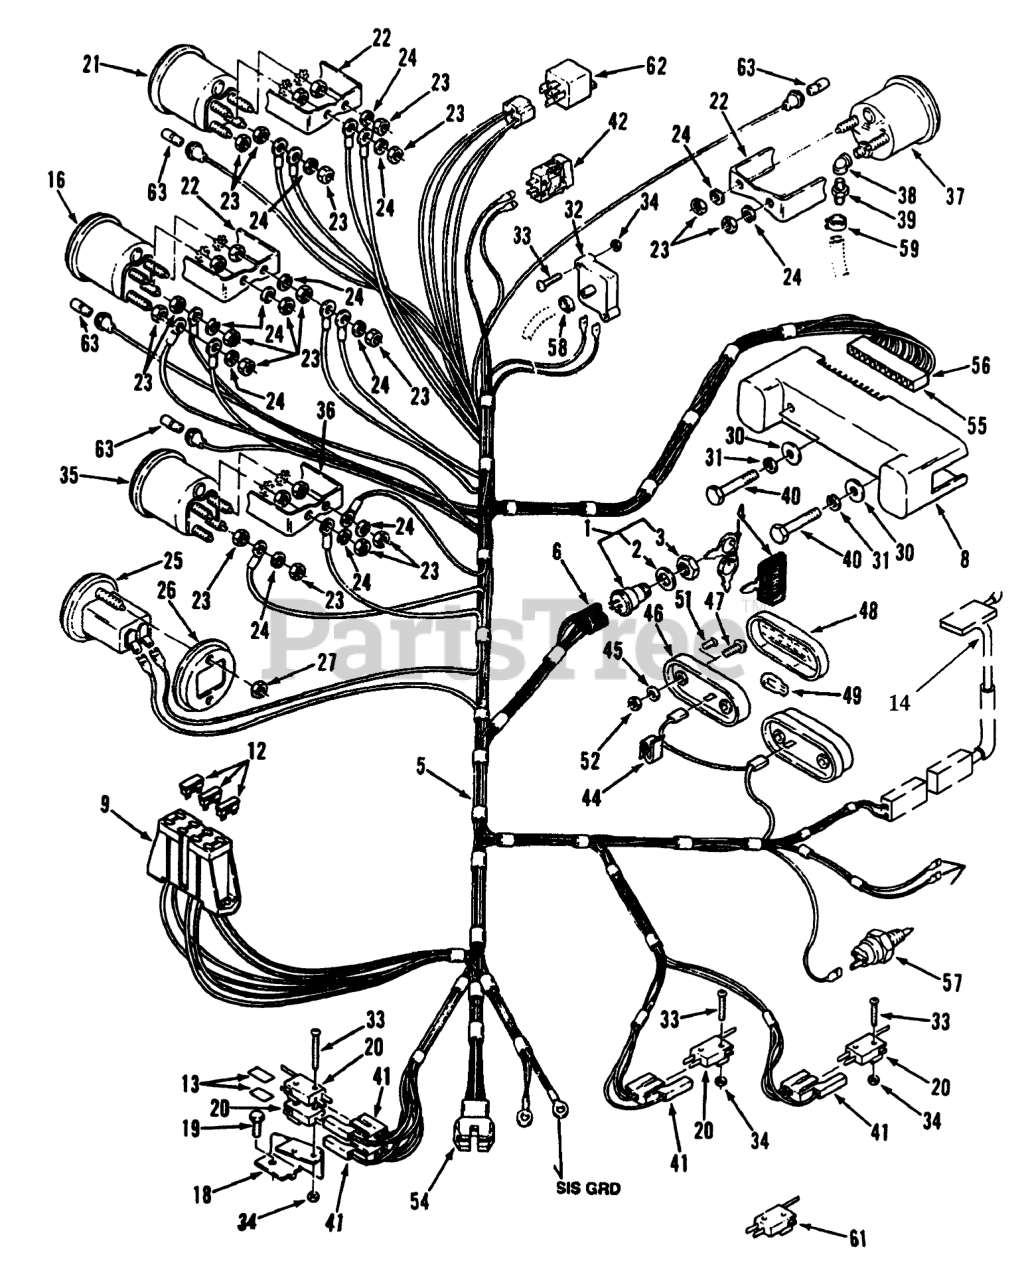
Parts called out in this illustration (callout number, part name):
1	SWITCH-IGNITION
2	Washer
4	Ignition Key
5	WIRING-HARNESS & DIA
6	CONNECTOR-5 WAY-SERV
8	CIRCUIT-BRD 8 LIGHT
9	FUSE-HOLDER 4 WAY
12	FUSE-10 AMP
13	BARRIER - SWITCH
14	SWITCH-SEAT
16	Gauge-Fuel (Includes Item 22)
18	Support-Switch
19	Bolt
20	SWITCH
21	Voltmeter (Includes Item 22)
22	CLAMP-MOUNTING
23	Nut
24	Lockwasher
25	Hourmeter (Includes Item 26)
26	Bracket-Mountin
27	Nut
30	WASHER-FLAT
31	WASHER-LOCK
32	SENSOR-AIR CLEANER
33	Screw
34	Bolt
35	Tachomebr (Includes Item 36)
36	MOUNTING-BRACKET
37	Gauge-Vacuum (Includes Item 22
38	ELBOW
39	FITTING STRAIGHT
40	SCREW
40	ELBOW-45 DEG
41	CONNECTOR BODY
42	Light Switch
44	Clip-Speed
45	WASHER-LOCK, INT
46	BASE-TAIL LIGHT
47	Screw
48	LENS-TAIL LIGHT
49	LIGHT BULB
51	NUT-HEX
52	NUT-HEX
54	9-CIRCUIT CAP
55	Connector-Male
56	Terminal
57	SENSOR-HYDRO OIL HOT
58	CLAMP-HOSE 5/16"
59	Clamp
61	SWITCH - CLUTCH
62	Relay
63	LAMP-MINIATURE GE 53X
